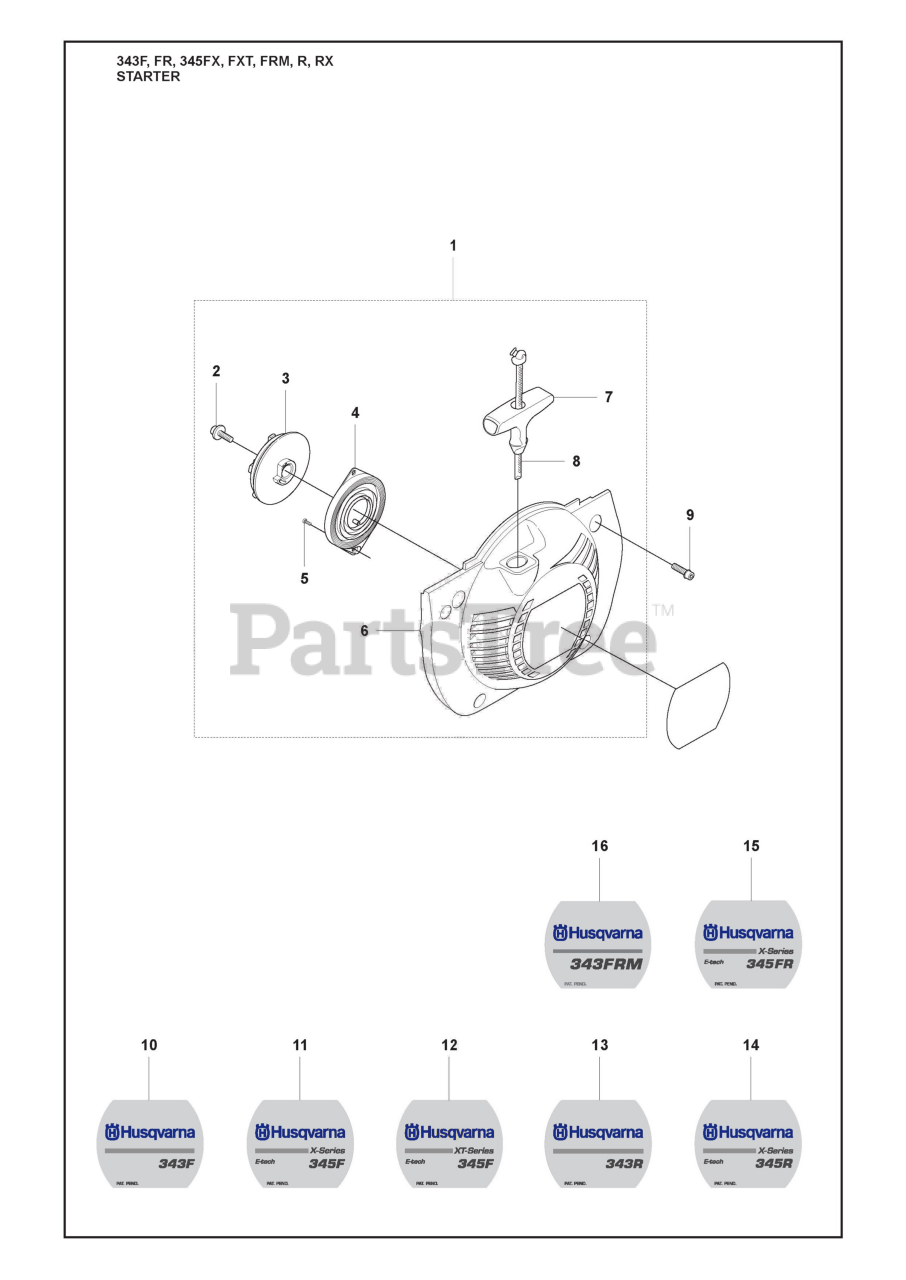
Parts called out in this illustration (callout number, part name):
1	%STARTER ASSY
3	STARTER PULLEY
4	RECOIL SPRING
6	STARTER DEVICE
7	STARTER HANDLE
8	STARTER ROPE
9	SCREW IHSCFM
10	LABEL STARTAP.343F
11	DECAL
12	LABEL STARTAP.345FXT
13	LABEL STARTAP.343R
14	DECAL
15	LABEL STARTAP.343FR
16	LABEL STARTAP.345FRM
